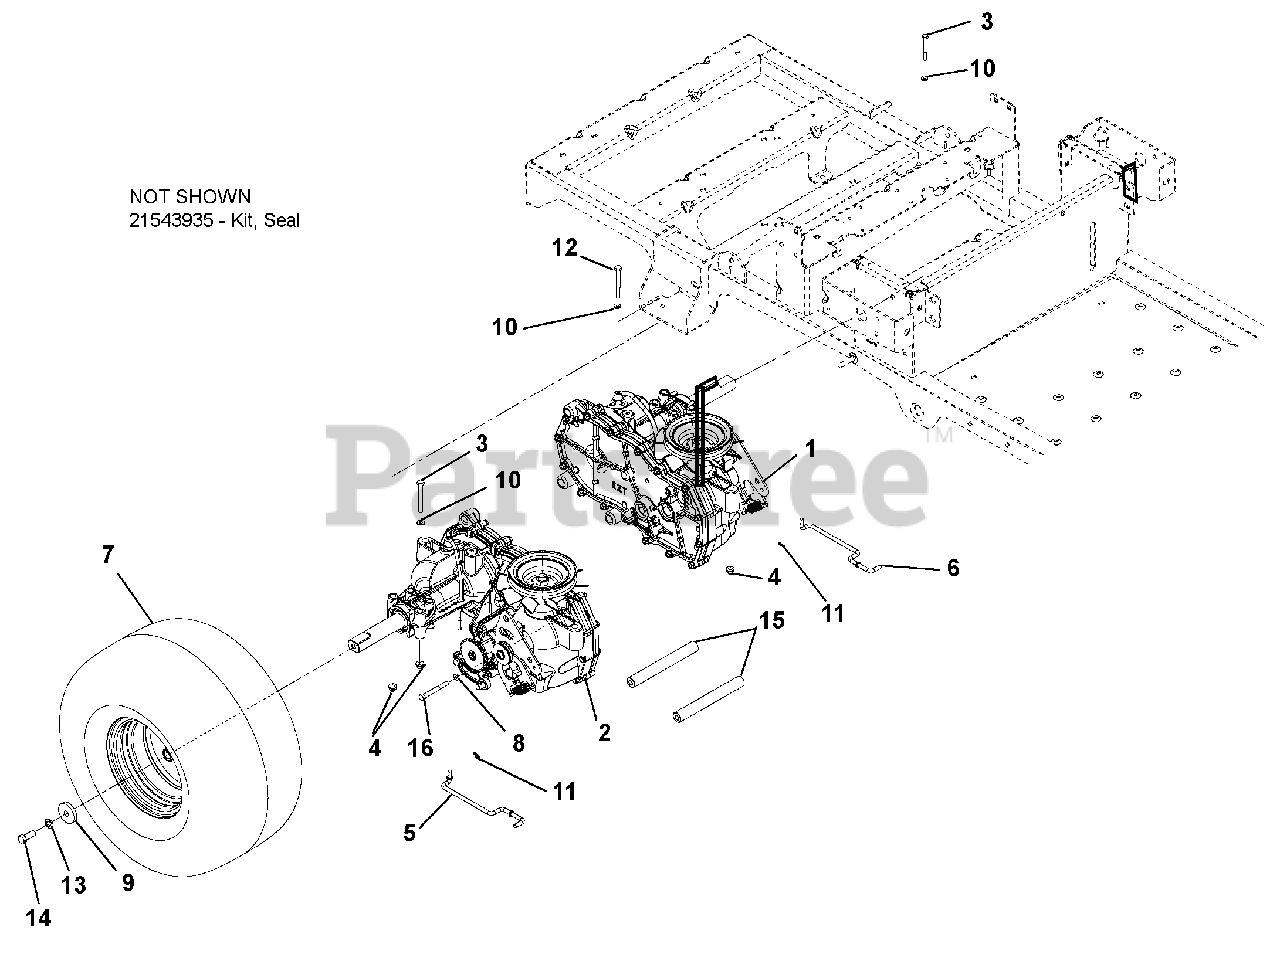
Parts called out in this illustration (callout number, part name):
1	Transaxle, Left Hand EZT D-Shaft (915146, 168)
2	Transaxle, Right Hand EZT D-Shaft (915146, 168)
3	Bolt, Hex .31-18 x 2.25
4	Nut 5/16-18 Flange Nyloc
5	Dump Valve, Right Hand
6	Dump Valve, Left Hand
7	Tire Assembly 18 x 6.5-8 2 Ply DSHAFT (915146, 168)
8	Washer, Flat Steel .406 x 1.00 x .188
9	Washer, Flat Steel .406 x 1.50 x .245
10	Washer, Flat Steel .38 x .875 x .083
11	Pin, Hair, Internal .06 x .18 x .77
12	Bolt, Hex .31-18 x 2.75
13	Washer, Locking .38 x .094 Regular
14	Bolt, Hex .38-16 x 1.00 YWZC EP30
15	Shaft, Transaxle Brace
16	BOLT, HEX .38-16 X 2.50
